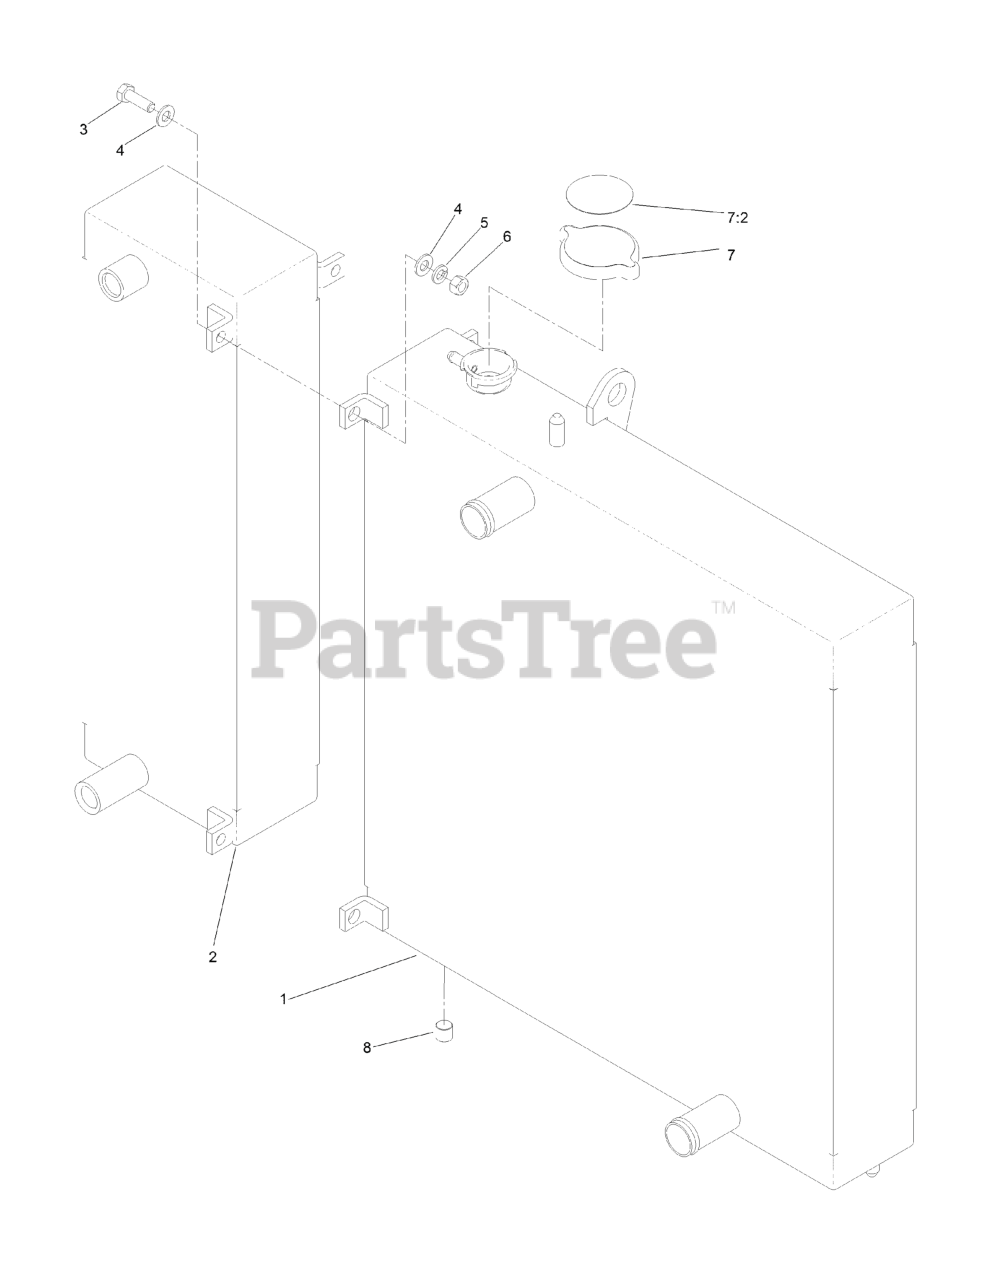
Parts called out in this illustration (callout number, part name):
1	RADIATOR
2	OIL COOLER
3	SCREW-HH
4	WASHER-PLAIN
5	WASHER-LOCK
6	NUT-HEX
7	RADIATOR CAP ASM
7:2	DECAL-DANGER
8	PLUG-PIPE
